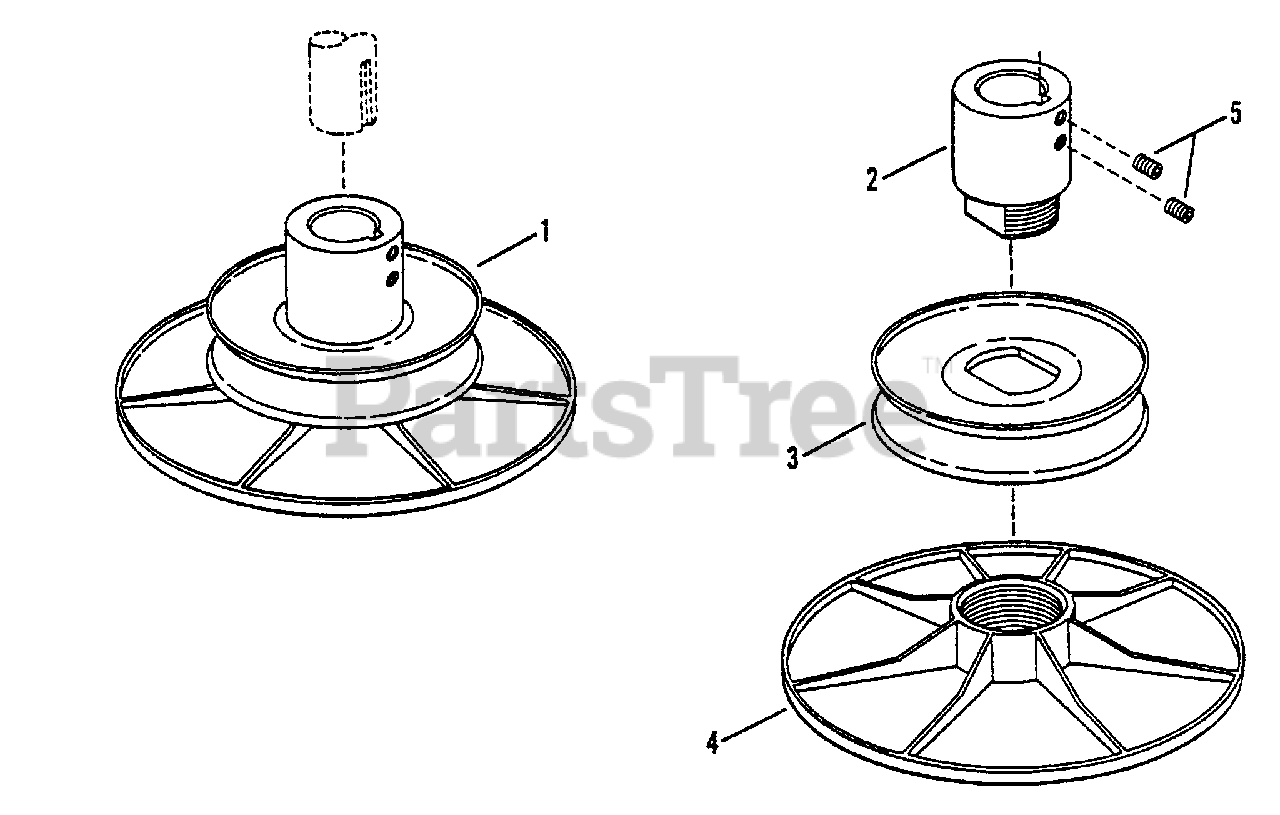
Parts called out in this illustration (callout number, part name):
1	ASSEMBLY, Drive Disc
2	HUB
3	PULLEY, Drive 5.75" O.D.
4	DISC, Drive
5	SCREW, 3/8-16 x 3/8" Set
